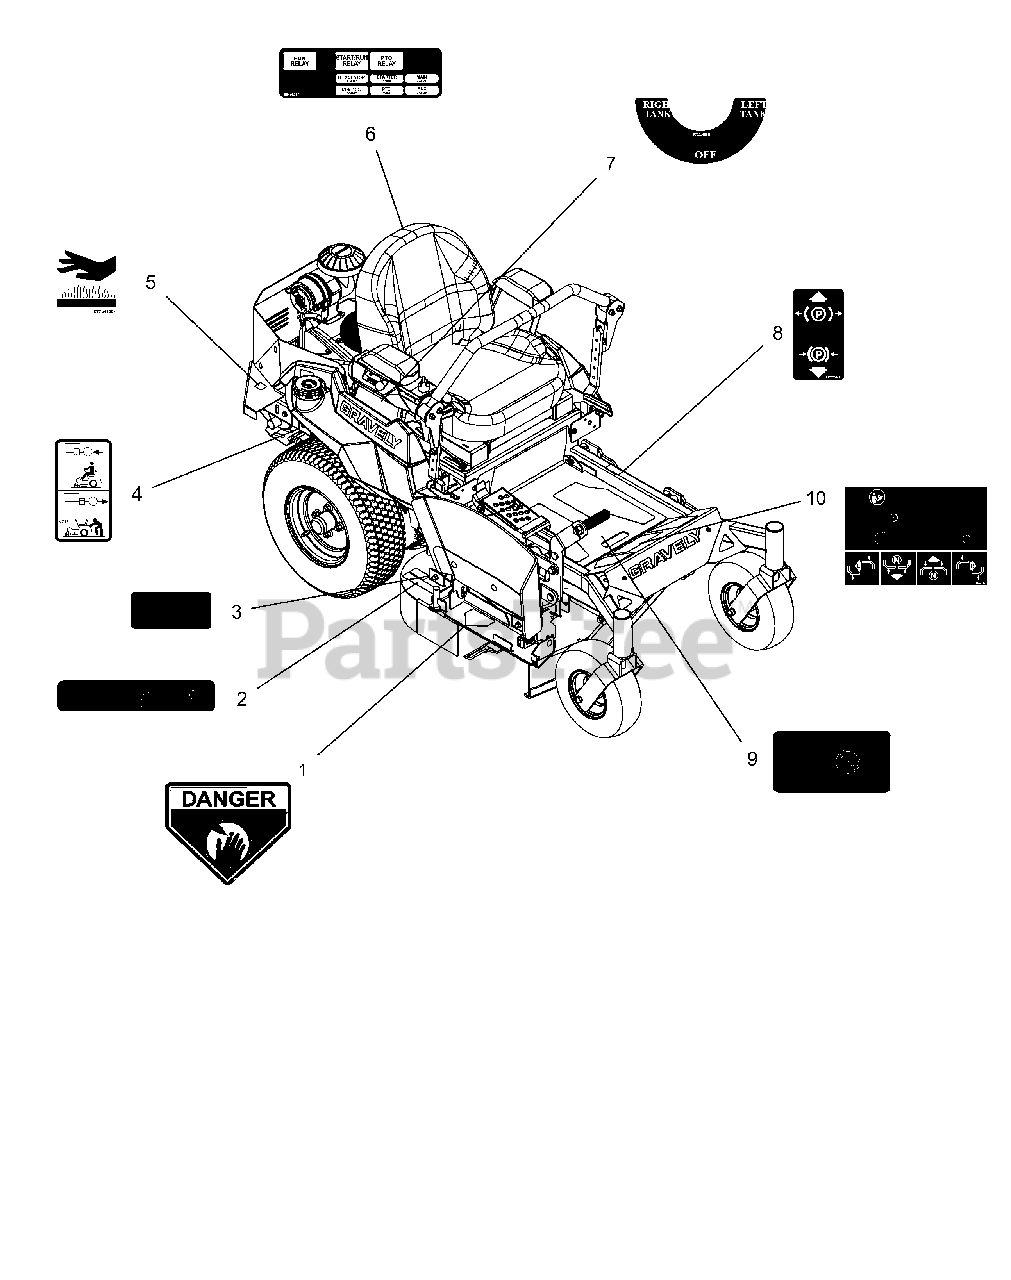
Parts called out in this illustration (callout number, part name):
1	DECAL, DANGER
2	DECAL, DECK SAFETY
3	DECAL, SAFETY - DECK GUARDING
4	DECAL, TRANSMISSION DISCONNECT
5	DECAL, HOT SURFACE
6	DECAL, FUSE BOX - COMPACT PRO
7	DECAL- FUEL CONTROL VALVE
8	DECAL, PARKING BRAKE LEVER
9	DECAL, SAFETY - GUARDING
10	DECAL, INSTR SAFETY
